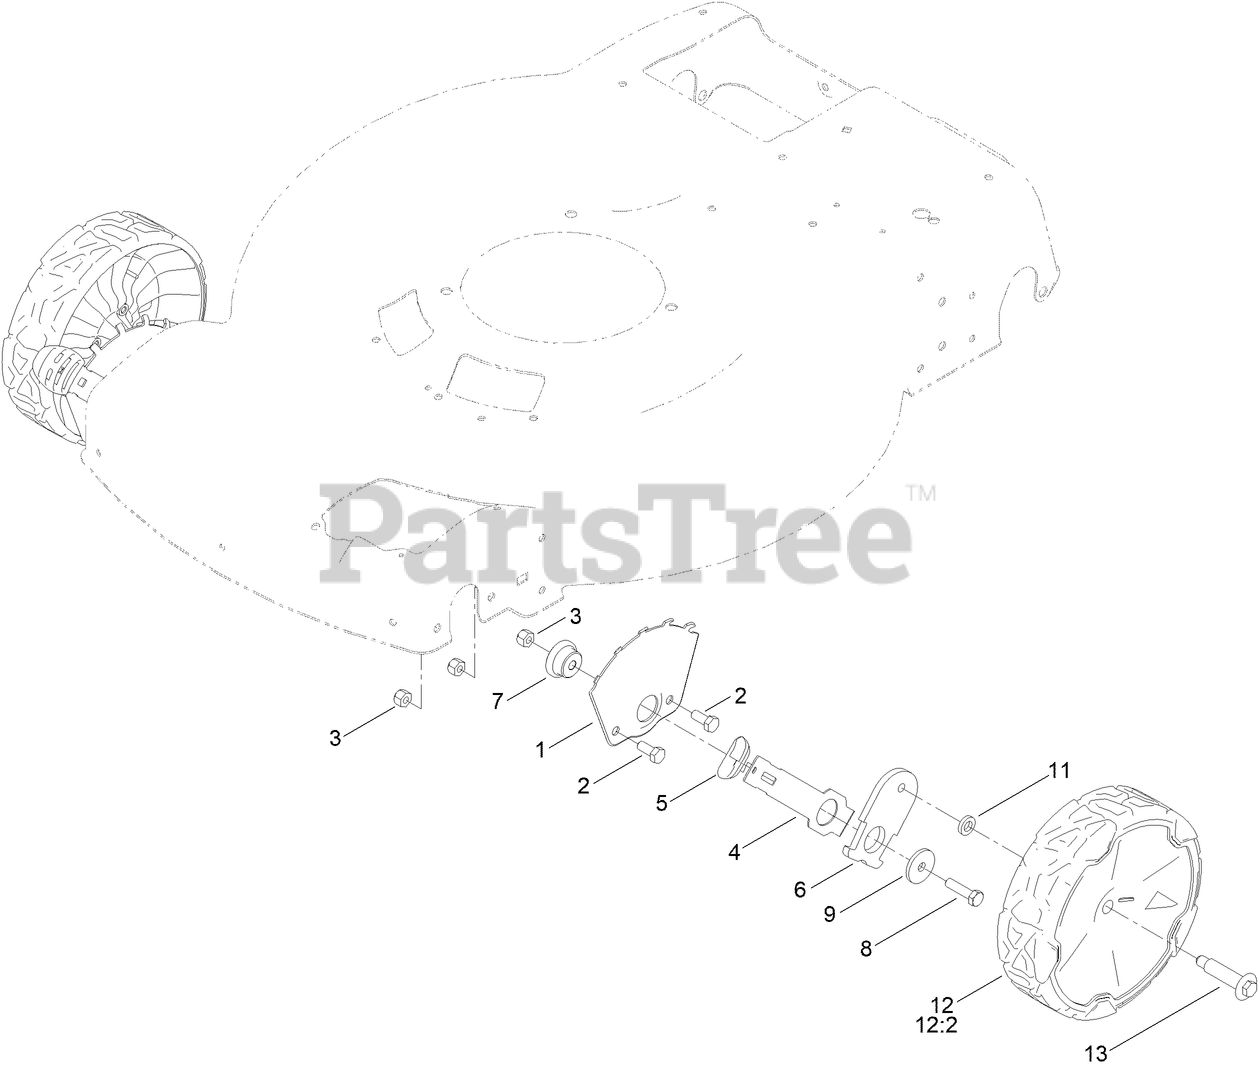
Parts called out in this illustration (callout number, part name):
1	PLATE-HOC,FRONT FSVQ WEDNESDAY
2	SCREW-HH
3	NUT-LOCK, NI
4	ARM-SPRING
5	KNOB-LEVER, HOC
6	ARM-PIVOT, FRONT
7	BUSHING-MOUNT, HOC
8	SCREW-HH
9	WASHER-FLAT
11	WASHER-WHEEL BOLT
12	ASM-WHEEL, 8" (BEARINGS)
12:2	BEARING-WHEEL
13	WHEEL BOLT
